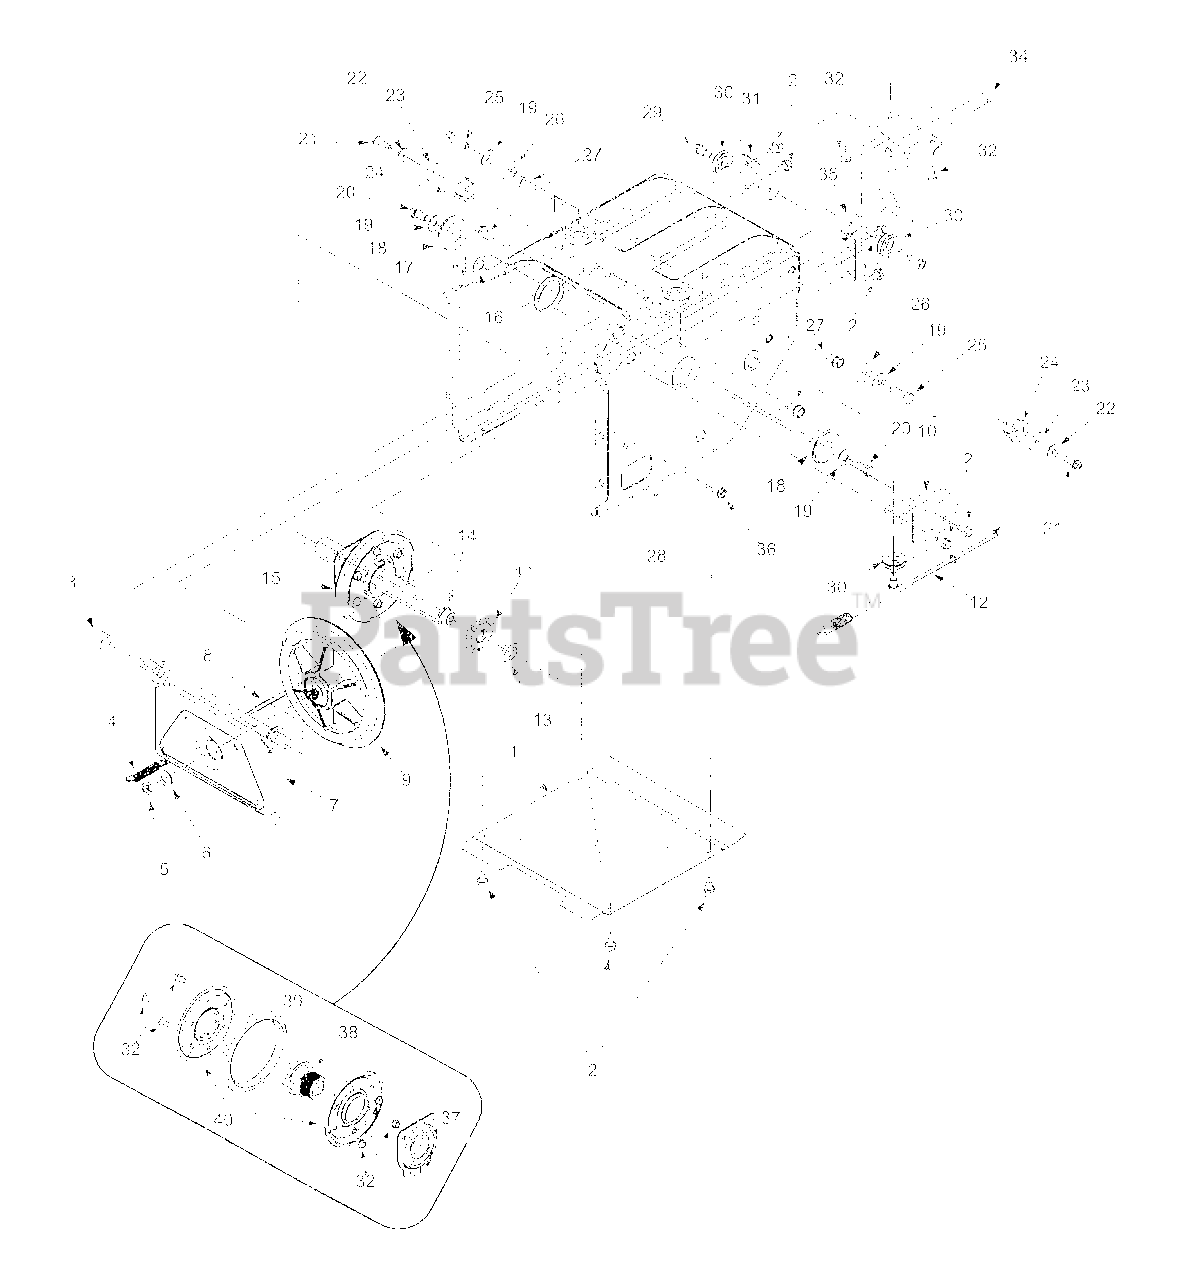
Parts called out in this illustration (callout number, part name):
3	Spacer .508 ID x .75 OD
4	Extension Spring
5	Jam Nut 3/8-24
6	Bell Washer .401 ID x .87 OD
7	Friction Whi Support Bracket
8	Drive Cable 39.88"
9	Friction Disc
10	Front Support Guide Bracket
11	10T Sprocket
12	Auger Cable 44.75"
13	Spacer .675 ID x 1" CID
14	Hex Track Shaft
15	Friction Wheel Assembly
16	Flat Washer .536 ID x .93 OD
17	Cotter Pin
18	Ball Bearing
19	Bell Washer .34 ID x .872 OD
20	Hex Cap Screw 5/16-18 x .625
21	Tap Screw 1/4-20 x .75
22	Bell Washer .265 ID x .75 OD
23	Flat Washer 1/4 ID x .93 OD
24	Hex Flange Bearing
25	Hex Cap Screw 5/16-18 x 1"
26	Shoulder Spacer
27	Tap Screw 5/16-18 x .625
29	Hex Screw 1/4-28 x .375
30	Cable Roler
31	Drive Cable Guide Bracket
32	Tap Screw 1/4-20 x.5
34	Shift Rod Assembly
35	Auger Cable Guide Bracket
36	Tap Screw 1/4-20 x 1.250
37	Friction Wheel Bearing
38	Friction Wheel Hub
39	Friction Wheel Rubber
40	Friction Plate
